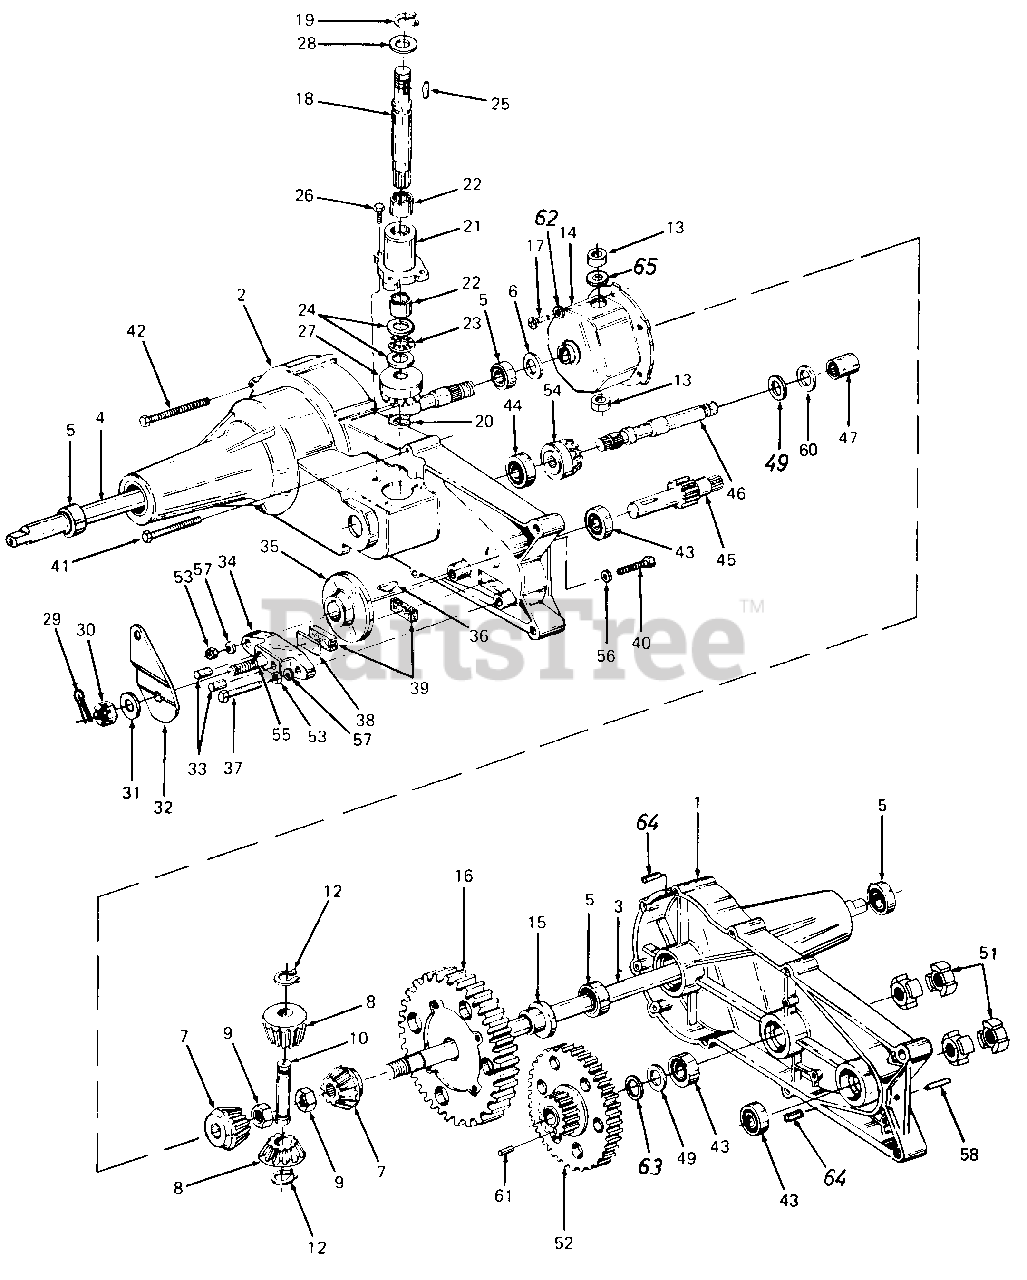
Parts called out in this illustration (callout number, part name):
1	Housing Half, L.H.
2	Housing Half, R.H.
3	Axle, L.H.
4	Axle, R.H.
5	Bearing, Ball
6	Washer, Flat, .76 x 1-1/8" x .306 Thk. Hdn.
7	Gear, Miter
8	Gear, Miter
9	Nut, Hex Jam Patch Lock, 1/2-20
10	Shaft, Cross
12	Ring, Snap
13	Bearing, Thrust
14	Housing Ass'y. Differential
15	Bearing, Flange, .75 I.D. x .587
16	Gear, Differential. 72 Tooth
17	Bolt ,Torx Head 1/4-28 x 5/8" Lg.
18	Shaft, Input
19	Ring, Snap
20	Ring, Retaining, Ext. 7/16 Dia.
21	Bearing, Input Housing
22	Bearing, Needle, 5/8 I.D. x .50 Lg.
23	Bearing, Thrust
24	Washer, Flat, 5/8 I.D. x 1.12 O.D. x .030 Thk.
25	Key #4 Hi-Pro, 3/32 x 5/8 Dia. (Hdn.)
26	Screw, Hex Patch Lock, 1/4-20 X 3/4 Lg.
27	Gear, Input Pinion, 17 Tooth
28	Washer, Flat, .62 I.D. x 1.0 O.D. x .030 Thk.
29	Pin, Cotter
30	Nut, Castle, 5/16-24
31	Washer, Flat, .343 x .88 x .062 Thk.
32	Arm, Brake Actuator
33	Pin, Actuating, 5/16 Dia.
34	Yoke, Brake
35	Disc, Brake
36	Key, Hi-Pro, 3/16 x 5/8 Dia.
37	Screw, Hex Patch Lock, 1/4-20 x 1.5 Lg.
38	Plate, Puck
39	Puck, Brake
40	Screw, Hex Cap, 1/4-20 x 1.5 Lg.
41	Screw, Hex Self-Tap, 1/4-20 x 2.0 Lg.
42	Screw, Hex Self-Tap, 1/4-20 x 2.75 Lg.
43	Bearing, Ball
44	Bearing, Ball
45	Shaft, Pinion w/11 Tooth Gear
46	Shaft, Drive
47	Bearing, Needle
49	Washer, Flat, 5/8 x 1.12 x .060 Thk.
51	Coupling
52	Gear, Tooth 60 & 17
53	Nut, Hex Jam, 1/4-20
54	Gear, Drive Pinion, 17 Tooth
55	Bolt, Square Hd. 5/16-24
56	Washer, Flat, .265 x .938 x .12 Thk.
57	Washer, Lock, 1/4
58	Pin, Roll, 3/16 Dia. x .50 Lg.
60	Bronze Thrust Brg. 5/8" I.D.
61	Dowel Pin 3/32" x 1/4"
62	Washer, HD. Spring Lock 1/4"
63	Seal, Grease
64	Pin Roll 3/16" Dia.
65	Washer Flat .62" I.D. x 1.0" O.D. x .20" Thk.
